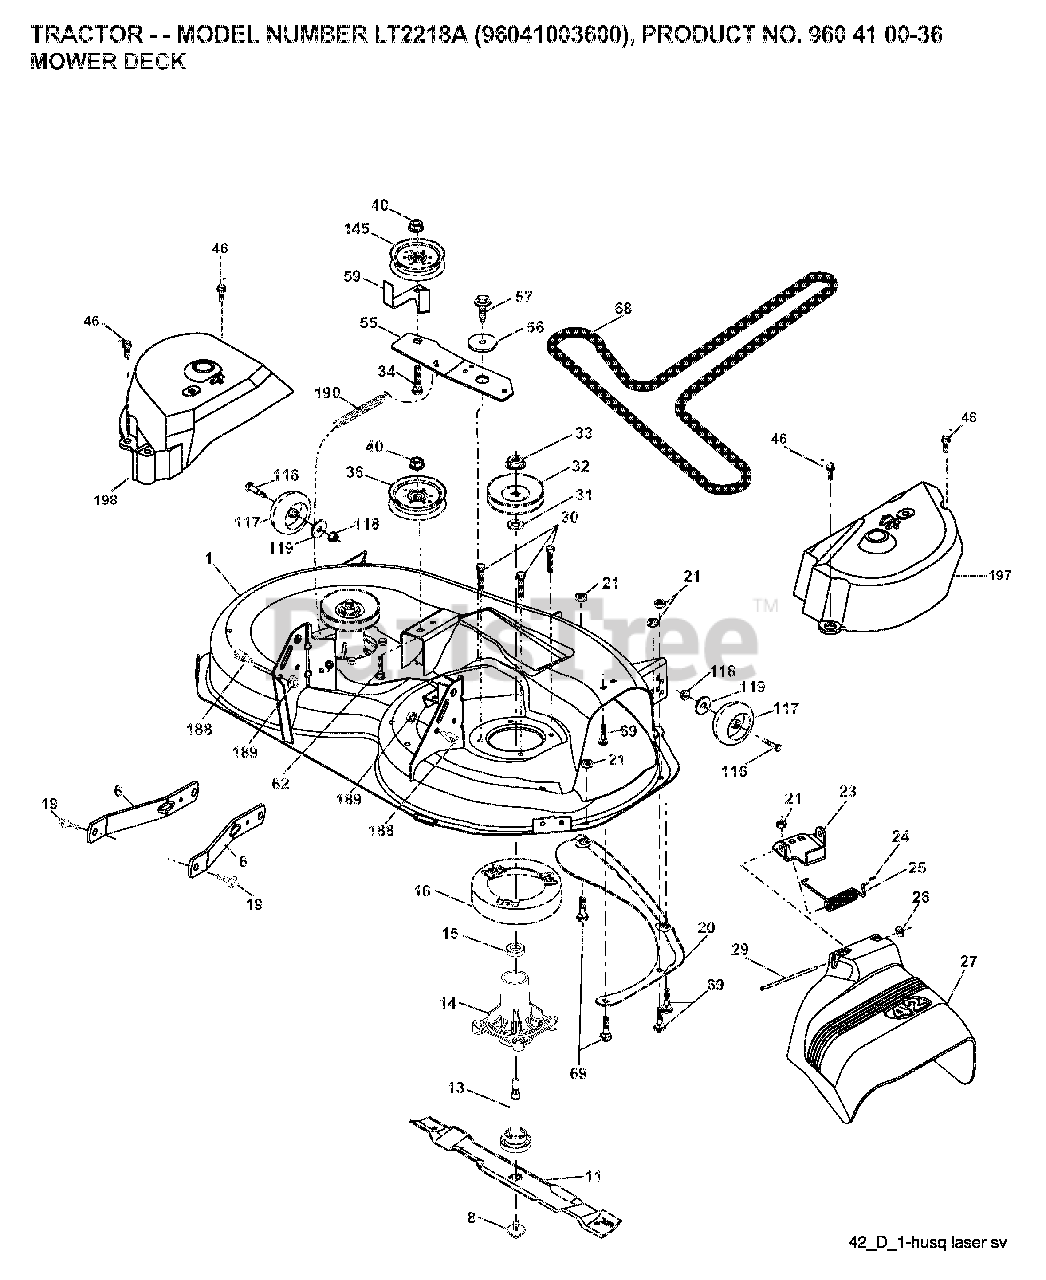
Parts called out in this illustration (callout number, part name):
1	DECK.WELDMENT.42"
6	ARM.SUSPENSION.MOWER.R
8	BOLT.WASHER.ASM.7/16-2
11	42" HI-LIFT BLADE
13	SHAFT.ASM.MDRL.N/GREASE.38
14	HOUSING MANDREL
16	STRIPPER, MWR ROUND
19	BOLT.SHOULDER
20	BAFFLE.VORTEX
21	LOCKNUT
23	BRKT.DEFLECTOR.38"2005+
24	CAP-SLEEVE LT
25	SPRING.TORSION.DEFLECT
26	NUT PUSH M
29	ROD.HINGE
30	SCREW, WASHER HEAD
31	WASHER.SPACER.MANDREL
32	PULLEY/MANDREL
33	NUT.FLANGE.LOCK.TOP
34	BOLT.3/8-16X1.50
36	PULLEY.IDLER.48"PRIMARY
40	NUT LOCK FLG 3/8-16 UNC
46	SCREW.1/4-20X5/8
55	IDLER.ARM
56	SPACER.RETAINER
57	SCREW 3/8-16X1
59	GUARD, BELT
62	BOLT
68	BELT V SECONDARY
69	BOLT
117	WHEEL.GAGE.HALF.SPOKED
118	LOCKNUT
119	WASHER
145	PULLEY.IDLER.2006
188	STUD.FASTNER.W/ANTI-ROTATE
189	NUT LOCK HEX FLANGE 5/16-18
190	SPRING.MOWER.DRIVE.ELECTRIC
199	SCREW 3/8-16X1/2
